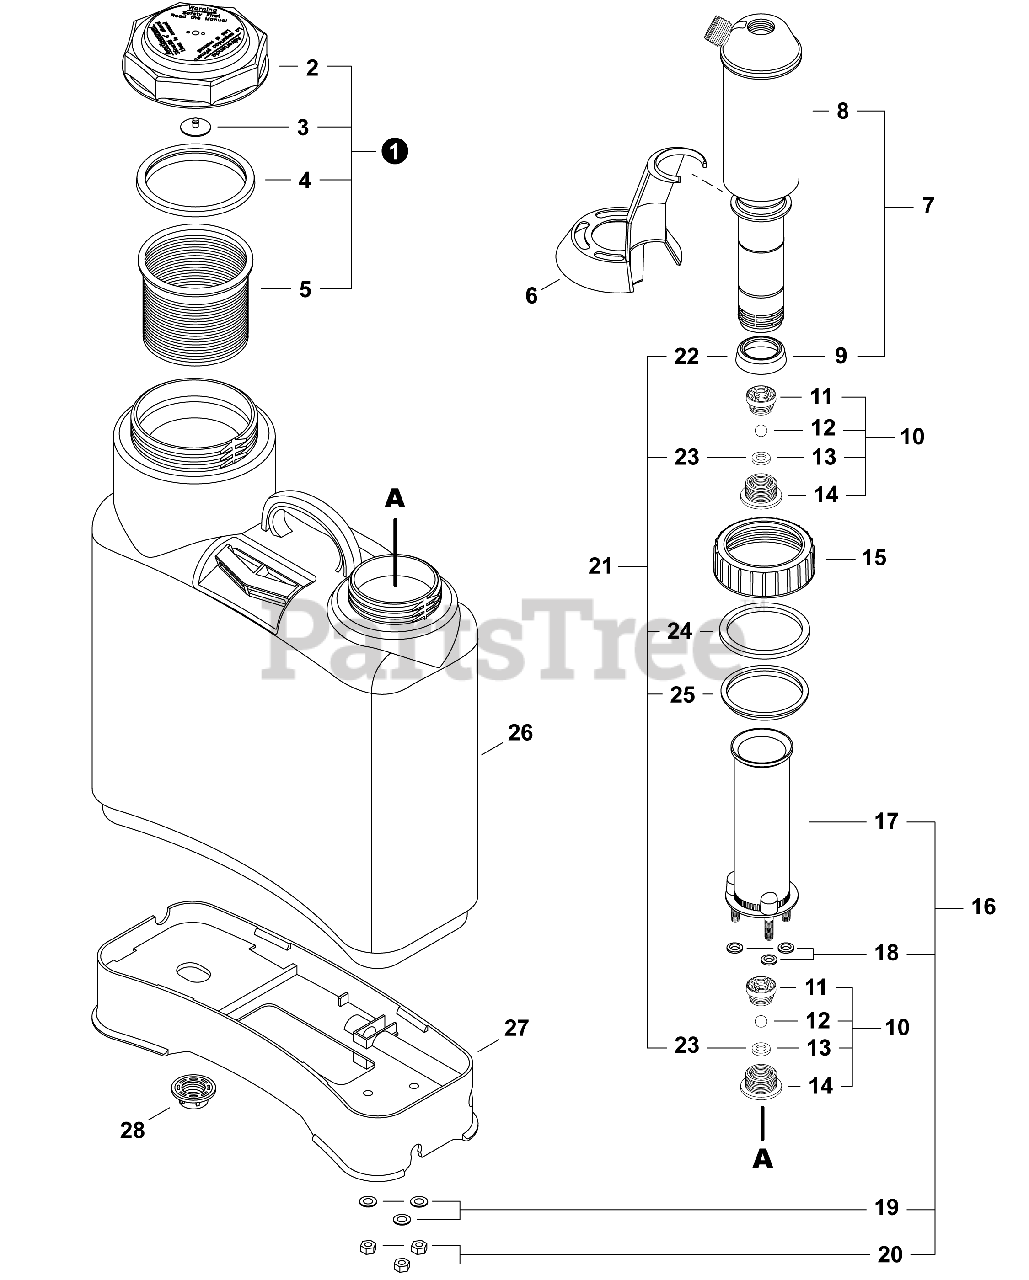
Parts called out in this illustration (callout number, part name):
1	CAP KIT, TANK
2	CAP, TANK
3	VALVE, CHECK - CAP
4	GASKET, BASKET
5	BASKET, FILTER
6	AGITATOR
7	CHAMBER KIT, PRESSURE
8	CHAMBER, PRESSURE
9	CUP, PLUNGER
10	VALVE ASSY, CHECK
11	BODY, VALVE
12	BALL, VALVE
13	WASHER
15	RING, LOCKING
16	CYLINDER KIT, PISTON
17	CYLINDER, PISTON
18	GASKET, STUD
19	WASHER
21	GASKET KIT, PUMP
22	CUP, PLUNGER
23	WASHER
24	WASHER, FELT
25	GASKET, CHAMBER
26	TANK, SPRAYER
27	BASE, TANK
28	NUT, TANK
